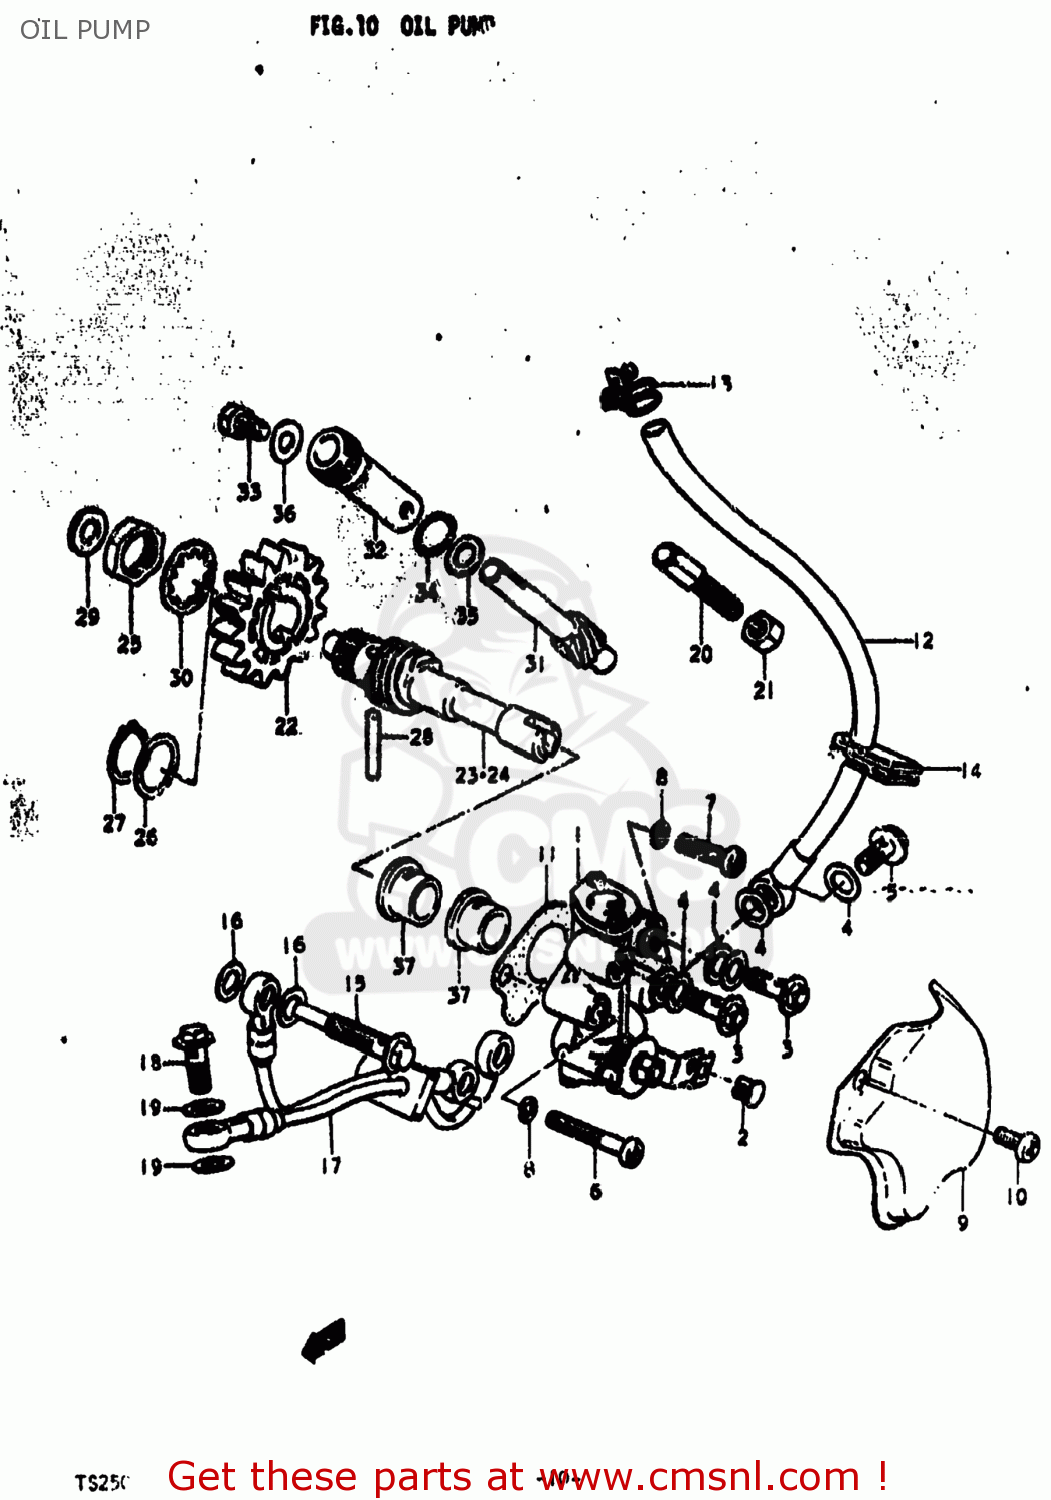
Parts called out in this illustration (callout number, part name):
1	PUMP ASSEMBLY,OIL
2	TERMINAL,CABLE
3	UNION BOLT
4	GASKET (NAS)
5	UNION BOLT
6	SCREW
7	SCREW
8	LOCK WASHER
9	CAP,OIL PUMP INSPECTION
10	SCREW
11	GASKET,OIL PUMP (MCA)
12	HOSE,OIL NO.1
13	CLAMP
14	GROMMET
15	BOLT,UNION 8X35
16	GASKET
17	HOSE,OIL NO.2
18	UNION BOLT
19	GASKET
20	BOLT
21	NUT
22	GEAR,OIL PUMP DRIVE
23	SHAFT,OIL PUMP IDLE GEAR
24	SHAFT,OIL PUMP IDLE GEAR
25	NUT
26	WASHER, INNER
27	CIRCLIP
28	ROLLER(4X23.8)
29	THRUST WASHER
30	WASHER,LOCK
31	GEAR,TACHOMETER DRIVEN
32	SLEEVE,TACHOMETER DRIVE
33	BOLT
34	O RING(D:1.3,ID:9.6)
35	WASHER(8X13.7X1)
36	WASHER
37	BUSHING
